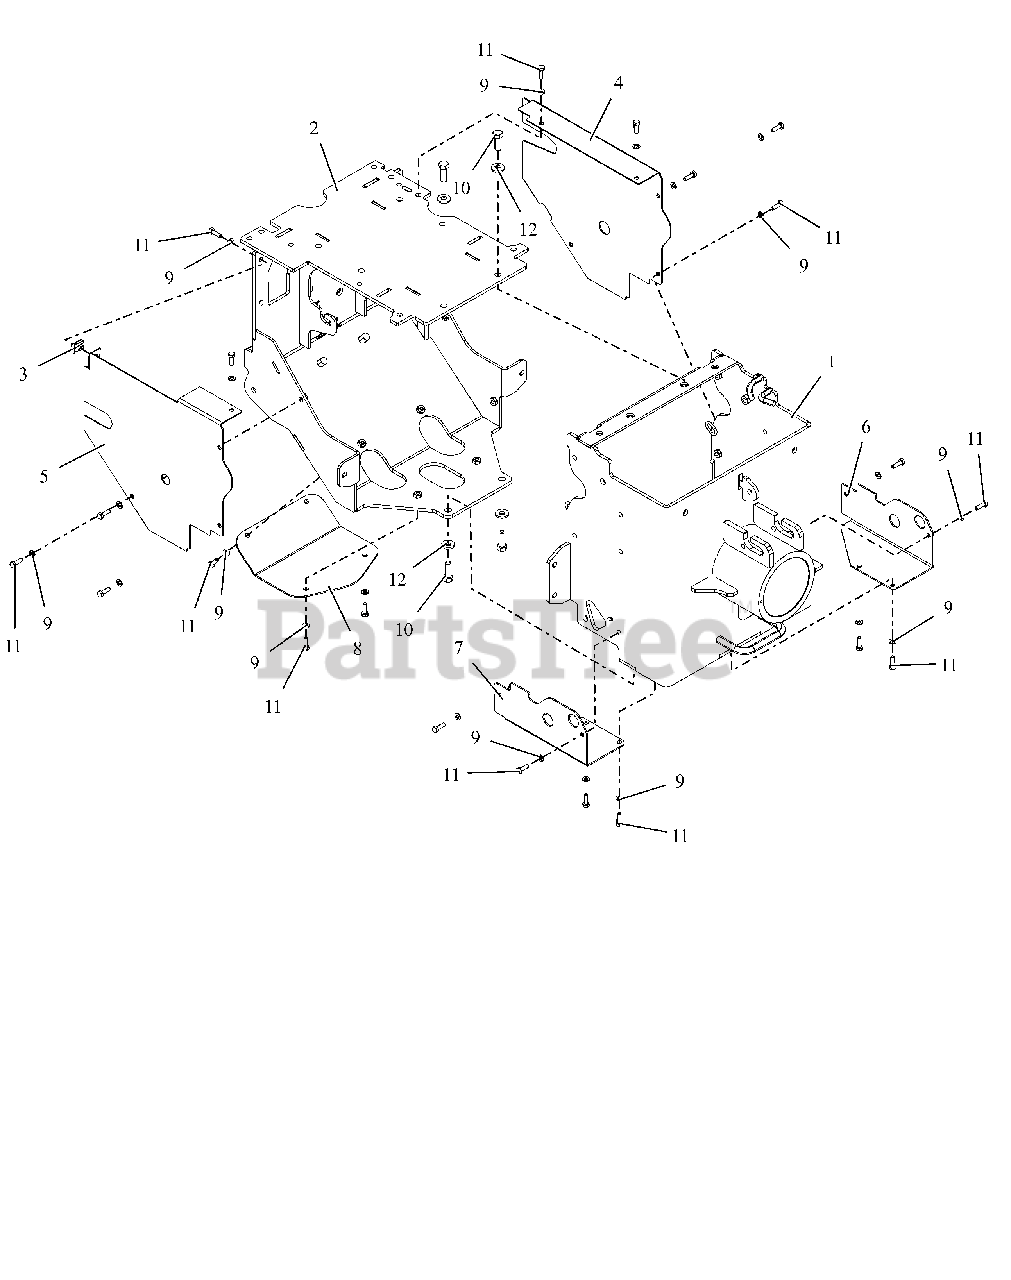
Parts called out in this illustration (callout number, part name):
1	WLDMT, FRONT HOUSING
2	WLDMT, FRAME BACK-KOHLER
3	NUT-RTNR M6X1
4	COVER, LH
5	COVER, RH
6	COVER, LH LOWER
7	COVER, RH LOWER
8	COVER, OIL
9	WSHR,LK-REG .250X.062 ZCC
10	BLT, HEX M10-1.5 X 30 G8.8 ZCC
11	BLT, HEX M6-1.0 X 20 G8.8 ZCC
12	WSHR,BLVL,M10 X 25 X 3.9 ZCMCH
